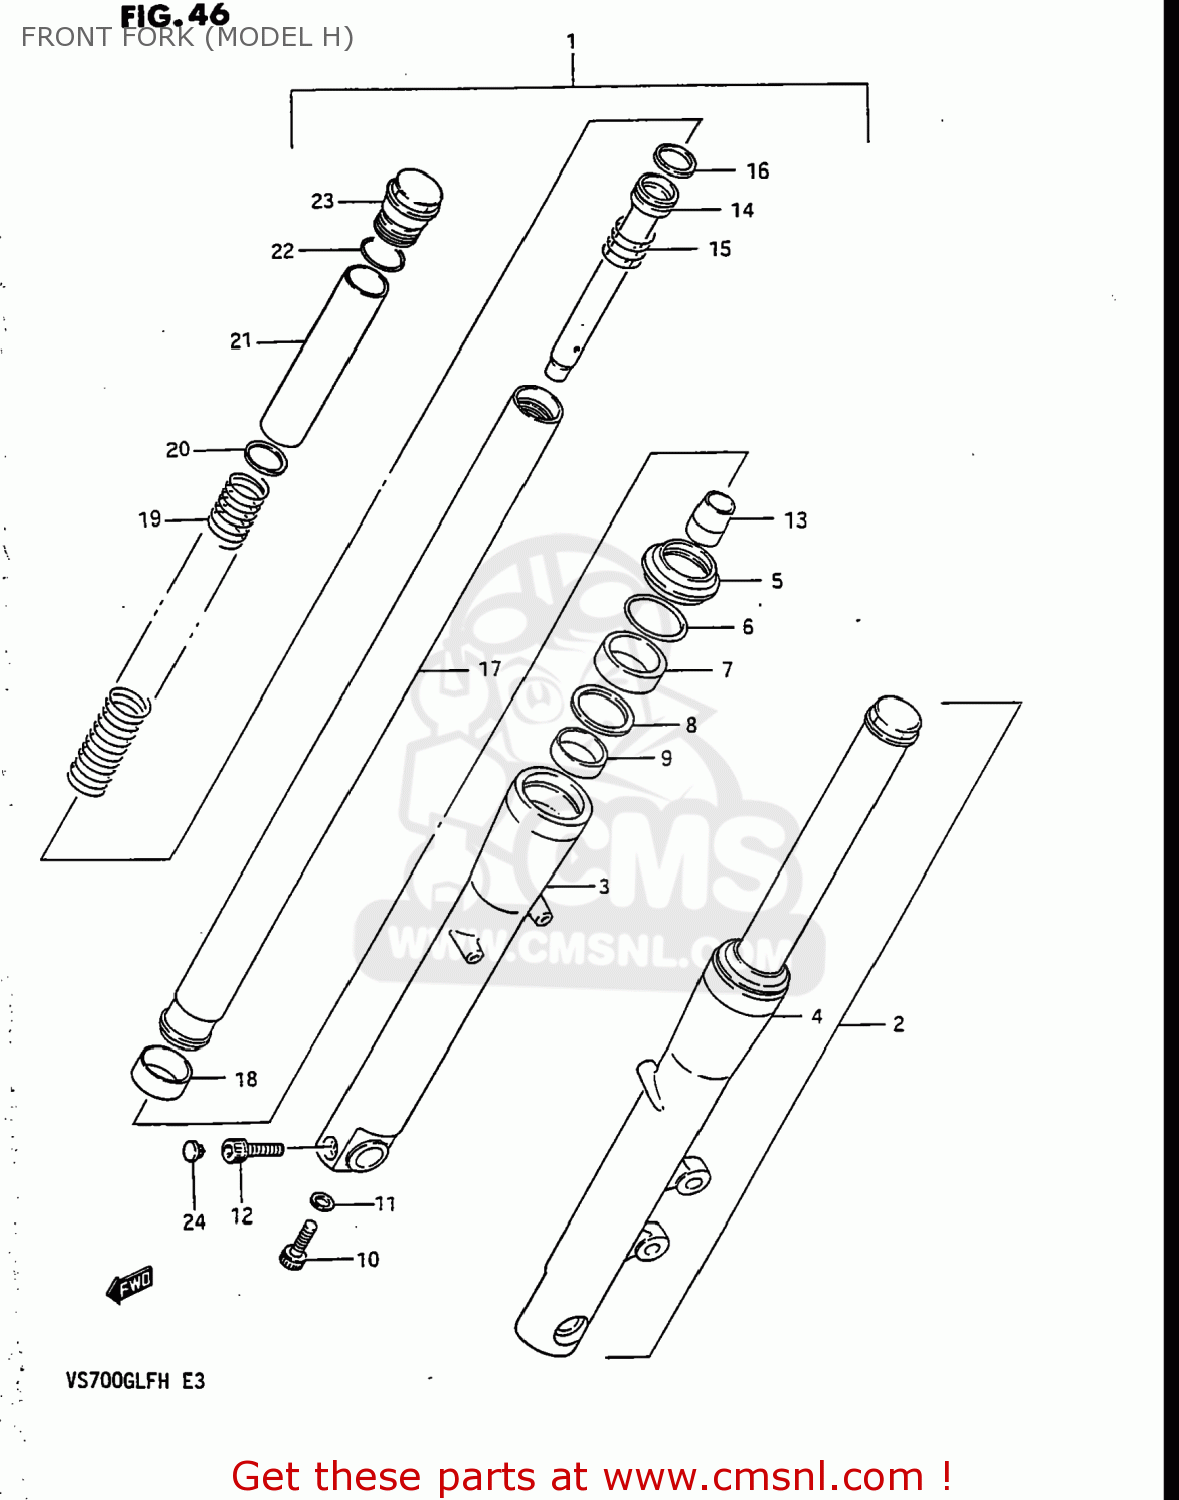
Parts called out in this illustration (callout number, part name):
1	DAMPER ASSEMBLY,RIGHT
2	DAMPER ASSEMBLY,LEFT
3	TUBE,OUTER,RIGHT
4	TUBE,OUTER,LEFT
5	SEAL,DUST
6	RING, STOPPER
7	OIL SEAL,FRONT FORK
8	SPACER,SEAL
9	BUSHING,GUIDE
10	BOLT(8X27)
11	GASKET (NAS)
12	BOLT, FRONT RH
13	PIECE,OIL LOCK
14	CYLINDER
15	SPRING,REBOUND
16	RING,PISTON
17	TUBE,INNER
18	PISTON
19	SPRING,FRONT FORK
20	SEAT,FRONT FORK SPRING
21	SPACER,FRONT FORK SPRING
22	O RING
23	BOLT,FR FORK
24	CAP(OD:14.5)
